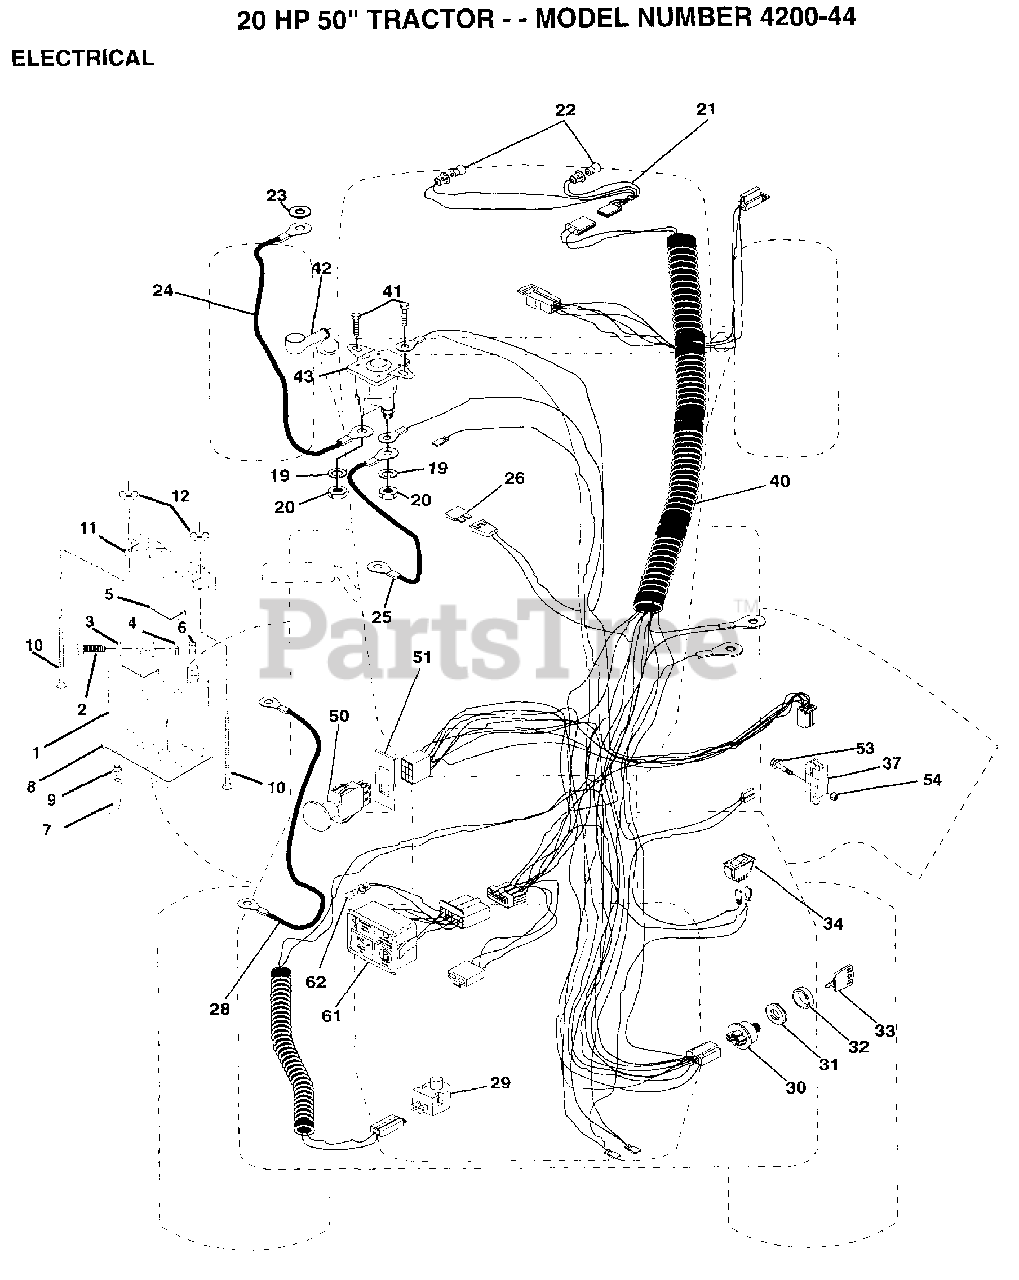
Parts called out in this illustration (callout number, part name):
2	BOLT LT
3	WASHER
4	LOCKWASHER
5	"CAP,BATTERY "
7	"DRAIN TU T, BATT"
8	"TRAY T, BATTERY"
9	HOSE CLAMP T
10	BOLT
20	NUT
22	HEADLAMP BULB
23	LOCKWASHER
24	"CABLE T, BATTERY"
25	CABLE-BATTERY T
26	FUSE HYT
28	CABLE T
29	SWITCH SEAT
32	COVER KEY SWITCH
33	KEY MLD GEN DELTA
34	SWITCH LT
37	SWITCH INTERLOCKT
40	HARNESS IGNITION
41	SCREW
51	RING RETAIN PTO
53	SCREW
54	"NUT,KEPS"
61	LIGHT.PKG.ASM.
62	BULB LIGHT T
